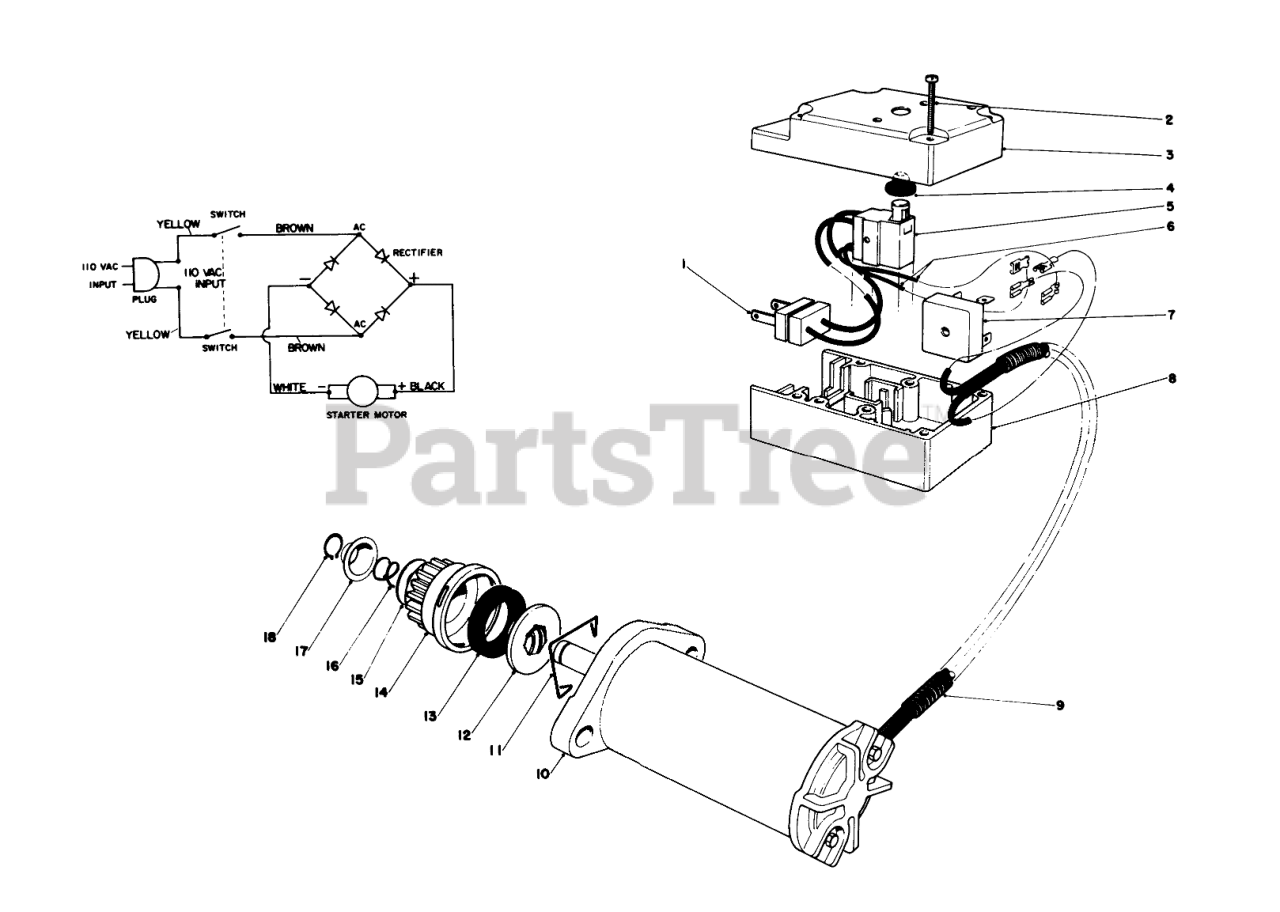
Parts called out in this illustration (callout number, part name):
1	Plug
2	SCREW-PLASTITE
3	Cap-Switch Housing
4	BOOT-SWITCH
5	SWITCH-STARTER
7	RECTIFIER-BRIDGE
8	Base-Switch Housing
9	CABLE COVER
10	Starter Motor
11	RETAINING CLIP
12	Helix Pinion Nut
13	RUBBER RING
14	Pinion
15	WASHER
16	COMP SPRING
17	PINION STOP
18	RET RING
